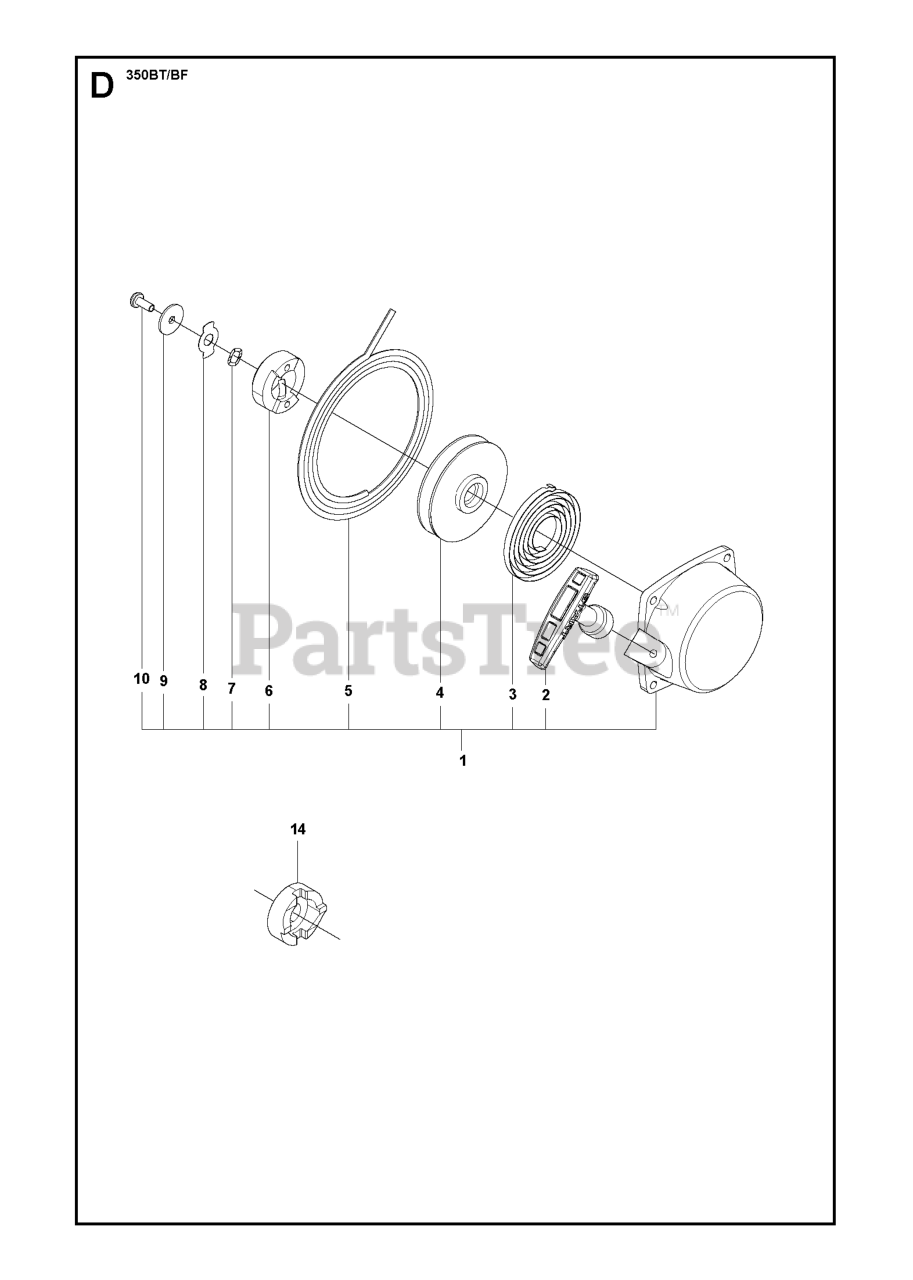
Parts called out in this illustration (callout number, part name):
1	STARTER ASSY
2	KNOB
3	SPRING
4	STARTER PULLEY
5	STARTER ROPE
6	STARTER PAWL
7	WASHER
8	RETAINER
9	WASHER
10	SCREW
14	PULLEY
